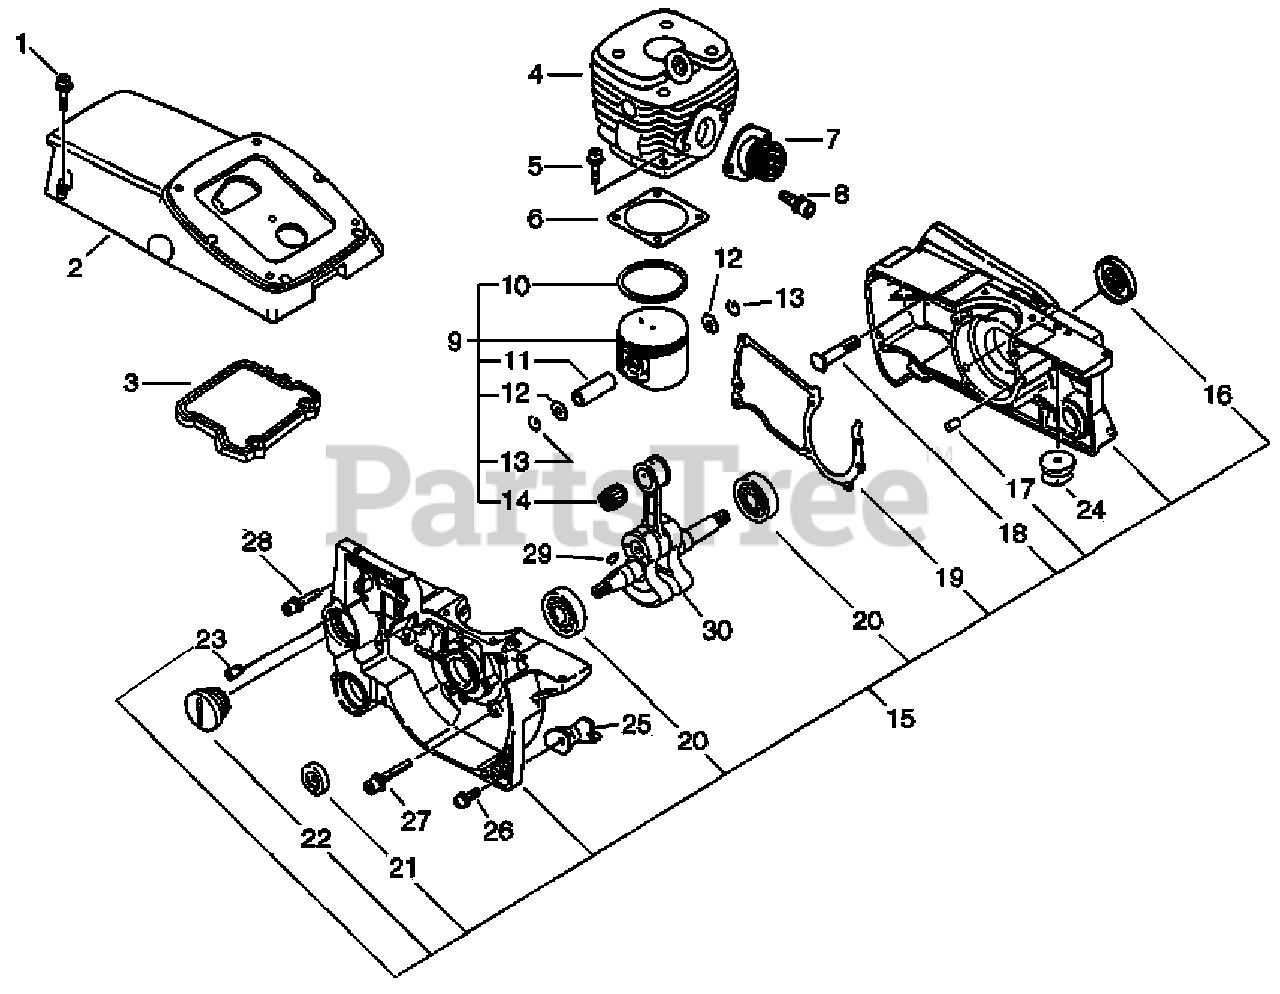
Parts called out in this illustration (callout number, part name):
1	SCREW - 5X20
2	COVER, ENGINE
3	CUSHION
4	CYLINDER
5	SCREW - 5X25
6	GASKET, CYLINDER
7	BELLOWS, INTAKE
8	SCREW - 5X14
9	PISTON KIT
10	RING, PISTON
11	PIN, PISTON
12	SPACER, PISTON
13	RING, RETAINING
14	BEARING, NEEDLE
15	CRANKCASE KIT
16	SEAL, OIL
17	PIN - LOCATING
18	STUD, GUIDE BAR
19	GASKET, CRANKCASE
20	BEARING, BALL - 6202
21	SEAL, OIL
22	CAP, OIL TANK
23	VENT, TANK
24	CUSHION - A
26	SCREW - 5X14
27	SCREW - 5X35
28	SCREW - 5X20
30	CRANKSHAFT ASSY
